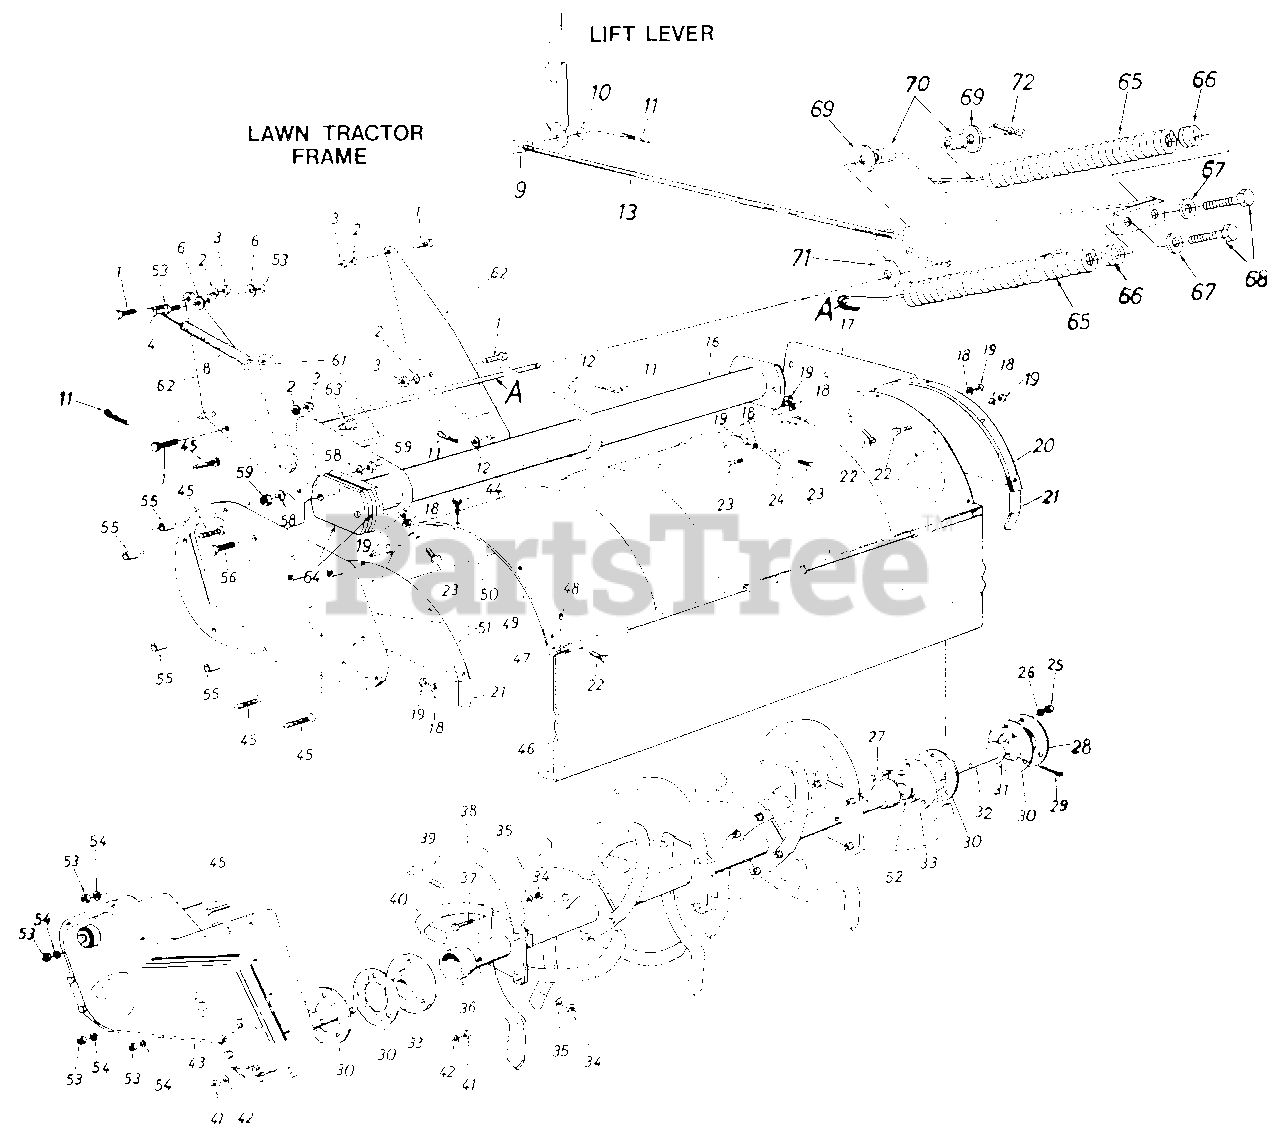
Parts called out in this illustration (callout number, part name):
1	Hex Bolt 3/8-24 x .88" Lg.
2	L-Wash. 3/8" l.D.-H.D.
3	Hex Nut 3/8-24 Thd.
4	Hex Bolt 1/4-20 x 1.25" Lg.
6	Bell-Wash. 1/4n I.D.
8	Ext. Spring 7.75n Lg.
9	Adjustment Ferrule 1/2-13 Thd.
10	Fl-Wash. .64" I.D. x 1.24 O.D. x .06
11	Intern. Cotter Pin 1/2" Dia.
12	Fl-Wash. .51 I.D. x 1.0" O.D. x .06
13	Lift Rod Ass'y. 39" Lg.
13	Comp. Spring 1.5" O.D. x 15" Lg.
13	Fl-Wash. .51" I.D. x 1.5n O.D. x .075"
16	Pivot Bracket Assembly
19	Hex Nut 5/16-24 Thd.
23	Hex Bolt 5/16-24 x .62" Lg.
24	Chute Pivot Bracket
25	Hex L-Nut 5/16-18 Thd.
27	Hex Bolt 5/16-18 x 1" Lg. (Grade 5)
30	Gasket for Brg. Housing
31	Fl-Wash. 1.25" l.D. x 2.0" O.D. x .061
32	Tine Shaft 1.25" Dia. x 6.25" Lg.
33	Bearing Housing w/Bearing
38	Tine 14" x 5/16"
39	Hex Bolt 3/8-24 x 2.25" Lg.
40	Tine 14" x 5/16"
43	Chain Case Ass'y. Comp.
44	Hex TT-Tap Scr. 5/16-18 x .62" Lg.
45	Hex Bolt 1/4-20 x 2.75" Lg.
48	Cotter Pin 1/8" Dia. x l" Lg.
53	Hex Nut 1/420 Thd.
54	L-Wash. 1/4" I.D.
55	Spacer .28" I.D. x .62" O.D. x .9" Lg.
56	Hex Bolt 1/2-20 x 1.5" Lg.
58	L-Wash. 1/2" l.D.
59	Hex Nut 1/2-20 Thd.
61	Idler Brkt. Support Arm Ass'y.
62	Pivot Brkt. Support
63	Shoulder Bolt
64	Support Plate
65	Helper Spring
66	Spring Insert
67	Fl-Wash. .34" I.D. x .68" O.D.
68	Hex Bolt 5/16-18 x 3.25" Lg.
69	Fl-Wash. 51" l.D. x 1.5n O.D.
70	Split Spacer .505" I.D. x .57" Lg.
71	Fl-Wash. 531n l.D. x 1.25" O.D.
72	Internal Cotter Pin 3/8" Dia.
